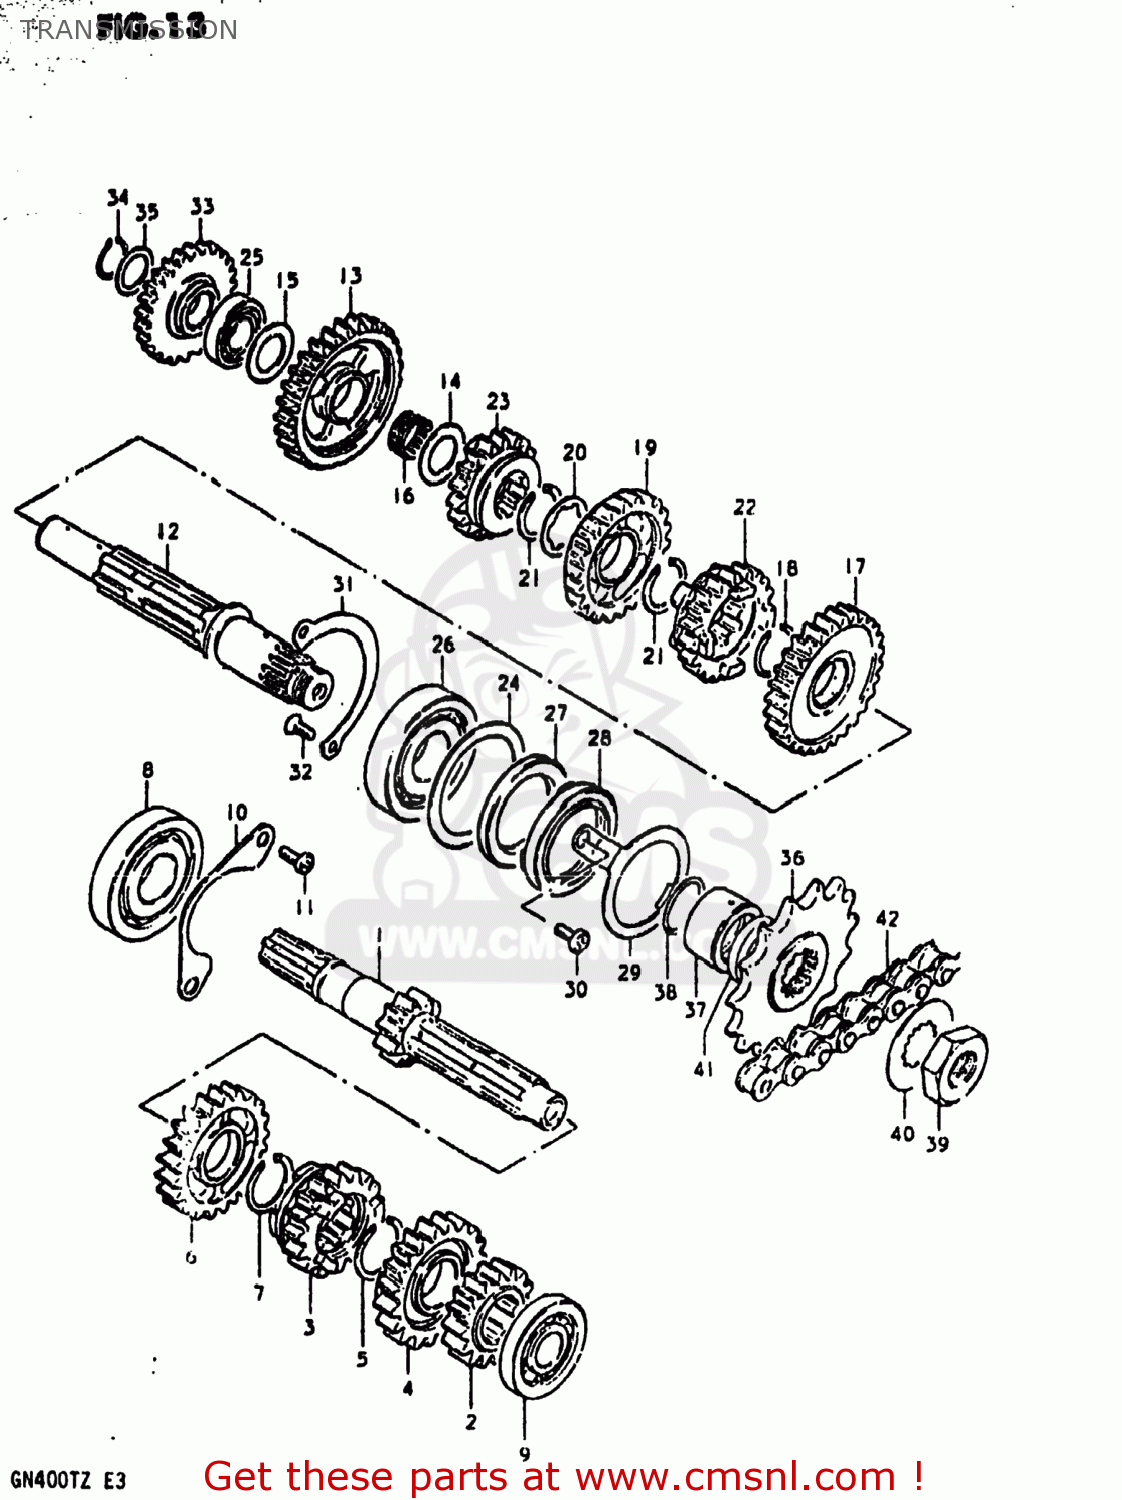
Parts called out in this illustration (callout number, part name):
1	SHAFT,COUNTER
2	GEAR,2ND DRIVE(NT:16)
3	GEAR,THIRD DRIVE
4	GEAR,FOURTH DRIVE
5	CIRCLIP
6	GEAR,FIFTH DRIVE
7	CIRCLIP
8	BEARING
9	BEARING
10	PLATE,COUNTERSHAFT BEARING
11	SCREW 6X12
12	SHAFT,DRIVE
13	GEAR,FIRST DRIVEN
14	WASHER
15	WASHER
16	BEARING(17X21X9.8)
17	GEAR,2ND DRIVEN(NT:27)
18	CIRCLIP
19	GEAR,THIRD DRIVEN
20	WASHER,LOCK
21	CIRCLIP
22	GEAR,FOURTH DRIVEN
23	GEAR,FIFTH DRIVEN
24	WASHER
25	BEARING(17X36X12)
26	BEARING(22X56X16)
27	OIL SEAL (30X47X5)
28	SEAL,OIL(30X47X7)
29	PLATE,DRIVESHAFT OIL
30	SCREW 6X12
31	RETAINER,DRIVE SHAFT BEARING
32	SCREW
33	GEAR,KICK STARTER IDLER(NT:25)
34	CIRCLIP
35	WASHER
36	SPROCKET,ENGINE(NT:16)
37	SPACER,ENGINE SPROCKET
38	O RING(D:2.5,ID:21)
39	NUT
40	WASHER,LOCK
41	SPACER
42	CHAIN,DRIVE #520SU-98
